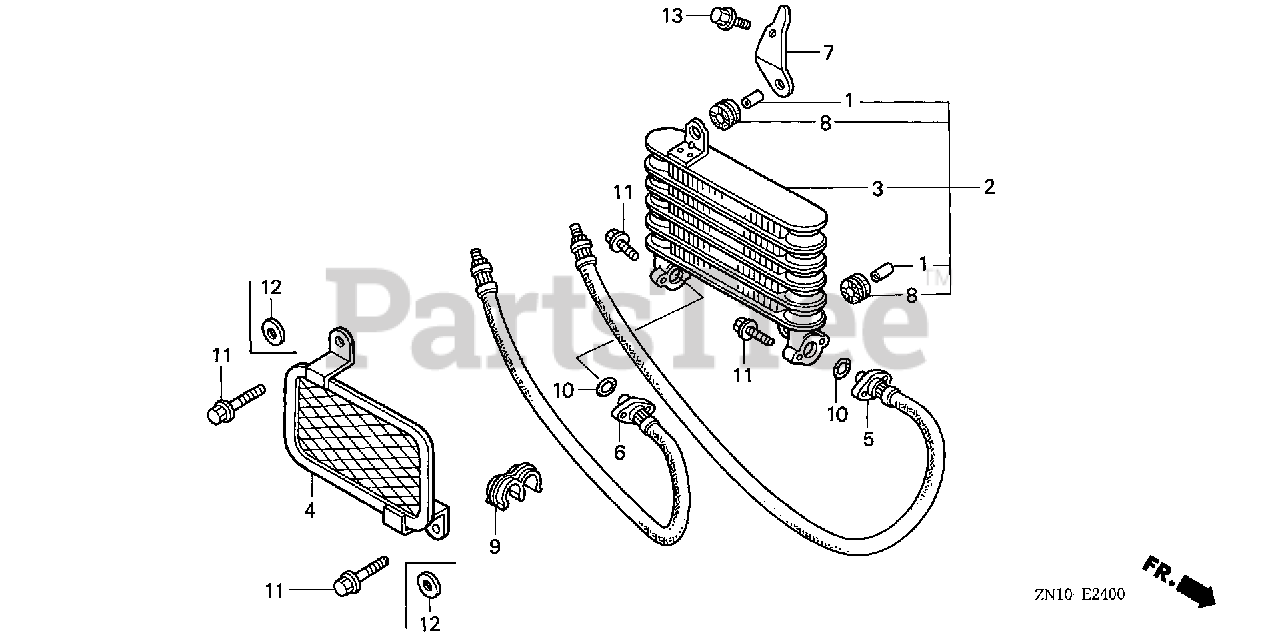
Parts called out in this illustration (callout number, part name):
1	COLLAR (12MM)
2	COOLER ASSY., OIL
3	COOLER, OIL
4	GRILLE, OIL COOLER
5	HOSE A, OIL
6	HOSE B, OIL
7	STAY, OIL COOLER
8	RUBBER, RADIATOR MOUNTING
9	CLAMP, HOSE (D13.5)
10	O-RING (10X2.6) (ARAI)
11	BOLT, FLANGE (6X22)
13	BOLT, FLANGE (6X14) (CT200)
